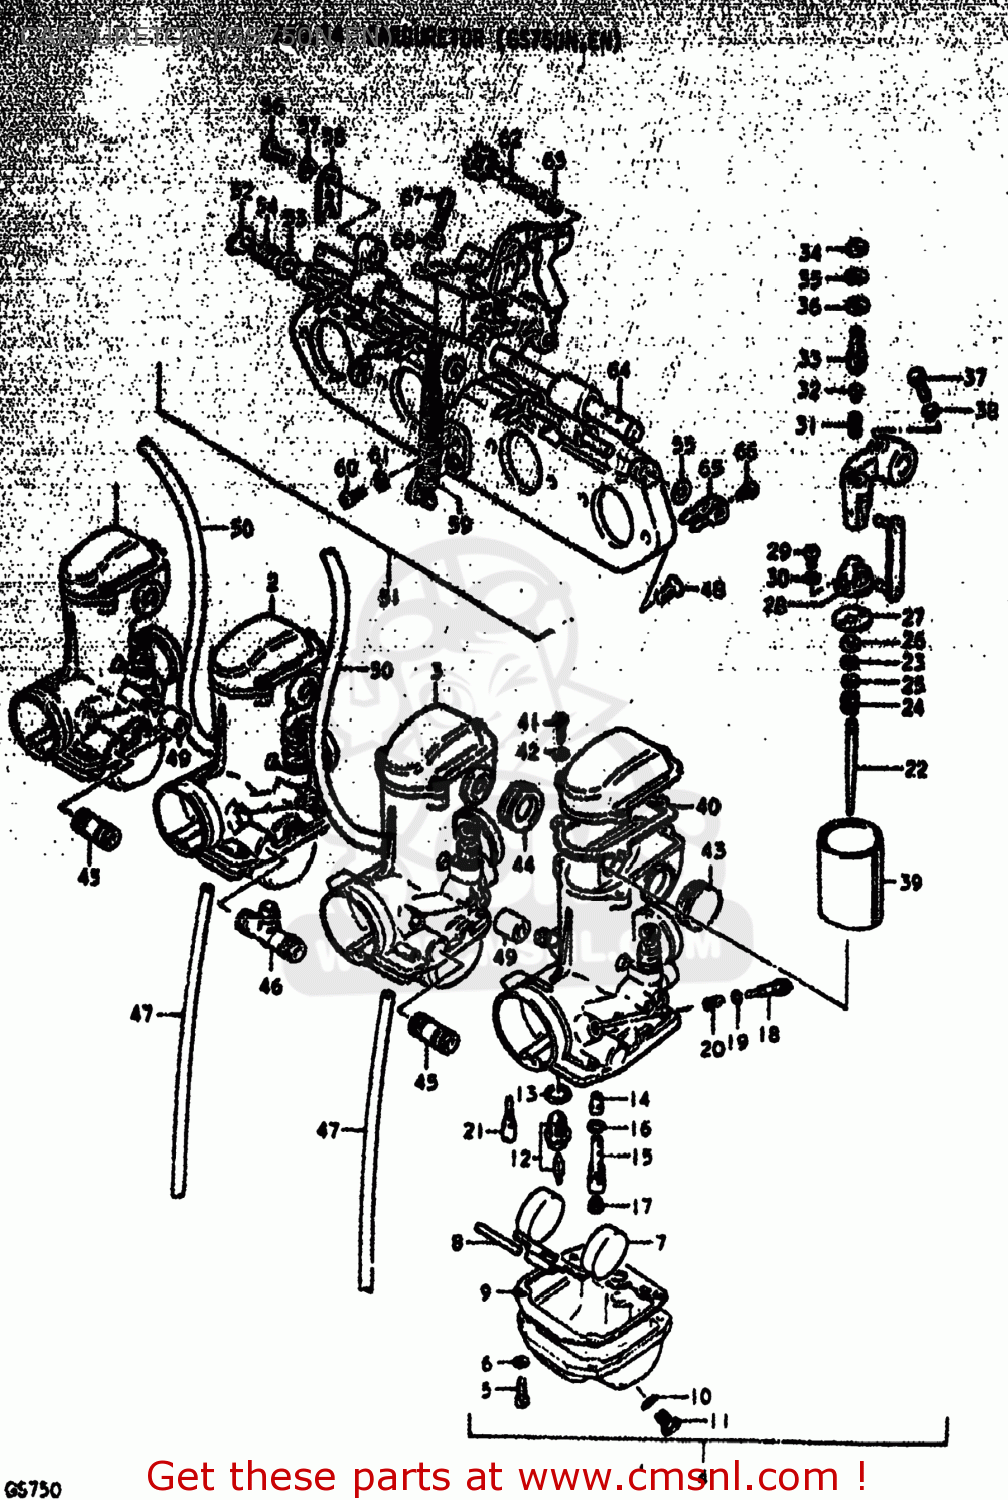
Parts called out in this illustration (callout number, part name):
1	CARBURETOR ASSEMBLY
2	CARBURETOR ASSEMBLY
3	CARBURETOR ASSEMBLY
4	CARBURETOR ASSEMBLY
5	SCREW
6	LOCK WASHER
7	FLOAT
8	PIN,FLOAT
9	GASKET,FLOAT CHAMBER (NAS)
10	O RING
11	SCREW
12	VALVE ASSEMBLY,NEEDLE
13	GASKET,VALVE SEAT (NAS)
14	JET,NEEDLE
15	PIPE,BLEEDER
16	O RING
17	JET,MAIN(102.5)
18	SCREW,PILOT AIR
19	O RING
20	SPRING
21	JET,PILOT
22	NEEDLE,JET
23	CLIP
24	SPRING
25	WASHER,JET NEEDLE
26	RING
27	PLATE,THROTTLE VALVE
28	CONNECTOR
29	SCREW
30	LOCK WASHER
31	SPRING
32	PIN,CARBURETOR
33	SCREW
34	NUT
35	LOCK WASHER
36	WASHER
37	BOLT
38	LOCK WASHER
39	VALVE,THROTTLE
40	GASKET (NAS)
41	SCREW
42	LOCK WASHER
43	PIPE,DELIVERY
44	SEAL
45	NIPPLE
46	NIPPLE
47	HOSE
48	SCREW
49	HOSE
50	HOSE 4.5X8X390
51	CARBURETOR ASSEMBLY
52	SHAFT,STARTER
53	WASHER
54	SPRING
55	WASHER,STARTER SHAFT
56	SCREW
57	LOCK WASHER
58	GASKET
59	SPRING,THROTTLE RETURN
60	SCREW
61	LOCK WASHER
62	ADJUSTER
63	SPRING,THROTTLE SCREW
64	SHAFT ASSEMBLY
65	LEVER,STARTER
66	SCREW
67	ADJUSTER,CABLE
68	NUT
